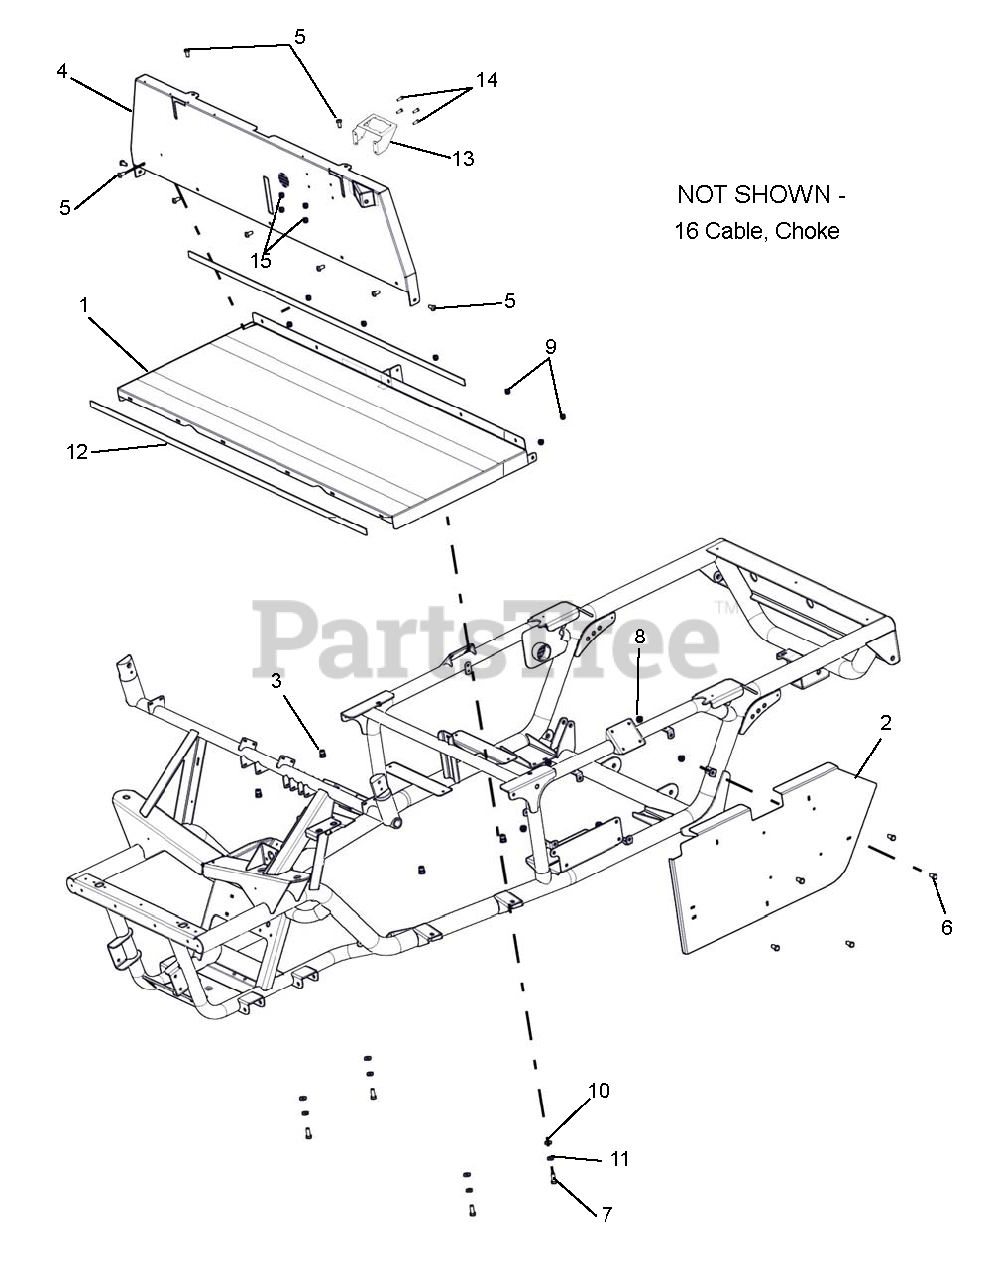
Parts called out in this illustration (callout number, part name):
1	WLDT-FLOOR
2	SIDE PANEL, WIDE
3	NUTZERT, 5/16-18 X .667 HEX Y
4	WLDT, KICK PANEL
5	SCR-MCH .25-20X.75 TXTR YWZC
6	@BLT-HEX .31-18X.75 GR5 YWZC
7	@BLT-HEX .31-18X1.00 GR5 YWZC
8	@NUT-LK-TOP-FLG .31-18 YWZC
9	@NUT-LK-TOP-FLG .25-20 YWZC
10	WASHER FLAT 5/16 HARD ASTMF436
11	@WSHR-LK .31X.078 REG YWZC
12	FOAM RUBBER 3/16X3/4 THK W/PSA
13	BRKT, MODULE EPA FUSE/RELAY
13	BRKT, MOUNT FUSE/RELAY MODULE
14	TTHMS 1/4-20X3/4 ZNYCR
15	NUT HEX FLG TL 1/4-20 ZNYCR
